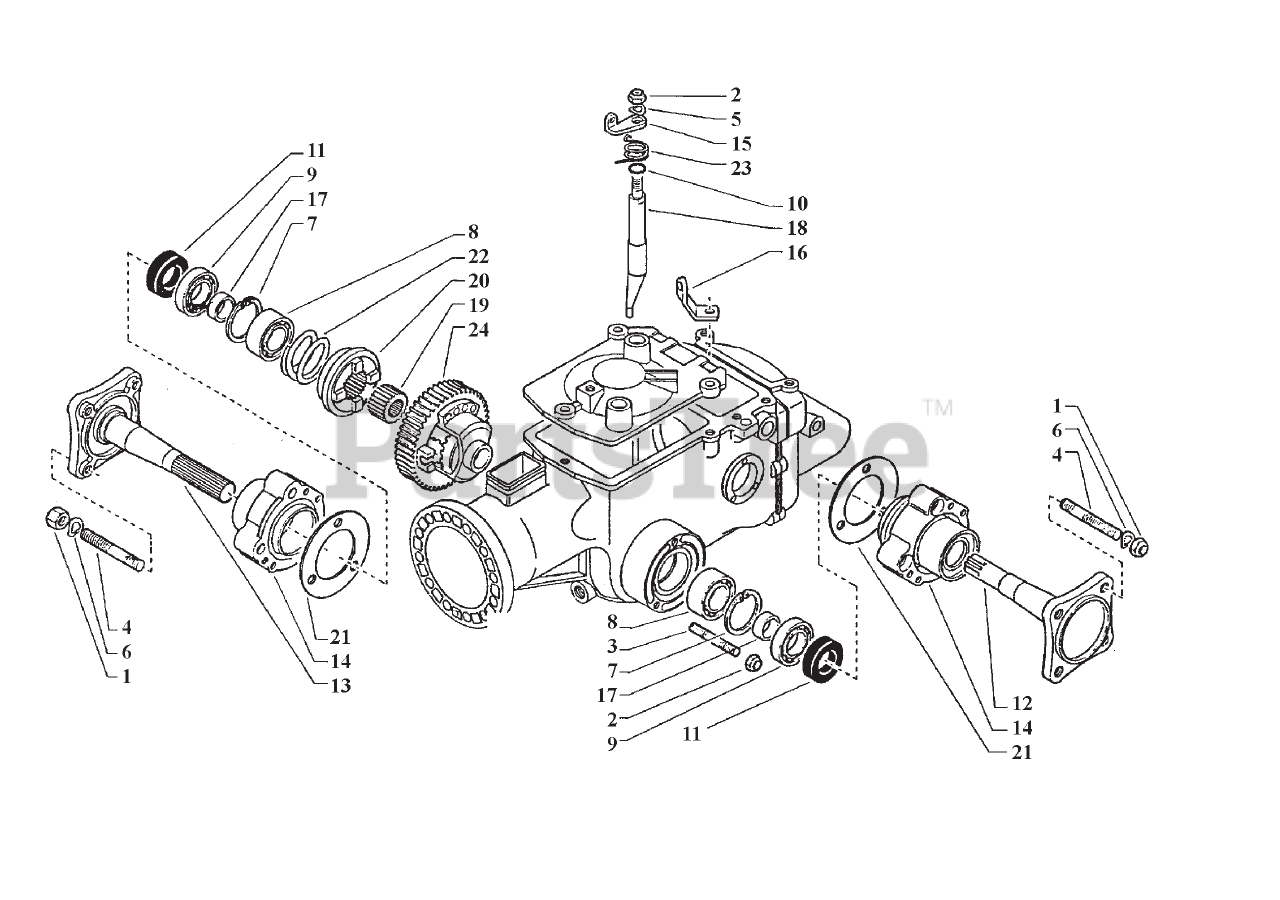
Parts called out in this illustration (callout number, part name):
1	NUT, M10
2	NUT, SELF LOCKING, M8
3	STUD, M8X46X20X12 GRADE 8
4	STUD, M10X40X24X12 GRADE 8
5	WASHER, FLAT, M8.4X17
6	WASHER, WAVEY, M10.5
7	SNAP RING, M47
8	BEARING, 6205 25X15X15
9	BEARING, 6005 25X47X12
10	O-RING
11	OIL SEAL, 30X40X7
12	AXLE, SHORT HALF
13	AXLE, LONG HALF
14	HUB FOR AXLE
15	LEVER, RELEASE
16	DIFFERENTIAL SHEATH STOP
17	RING, HALF AXLE
19	SPACER GEAR
20	COUPLING, FRONT
21	GASKET
22	SPRING
23	SPRING
24	DIFFERENTIAL
